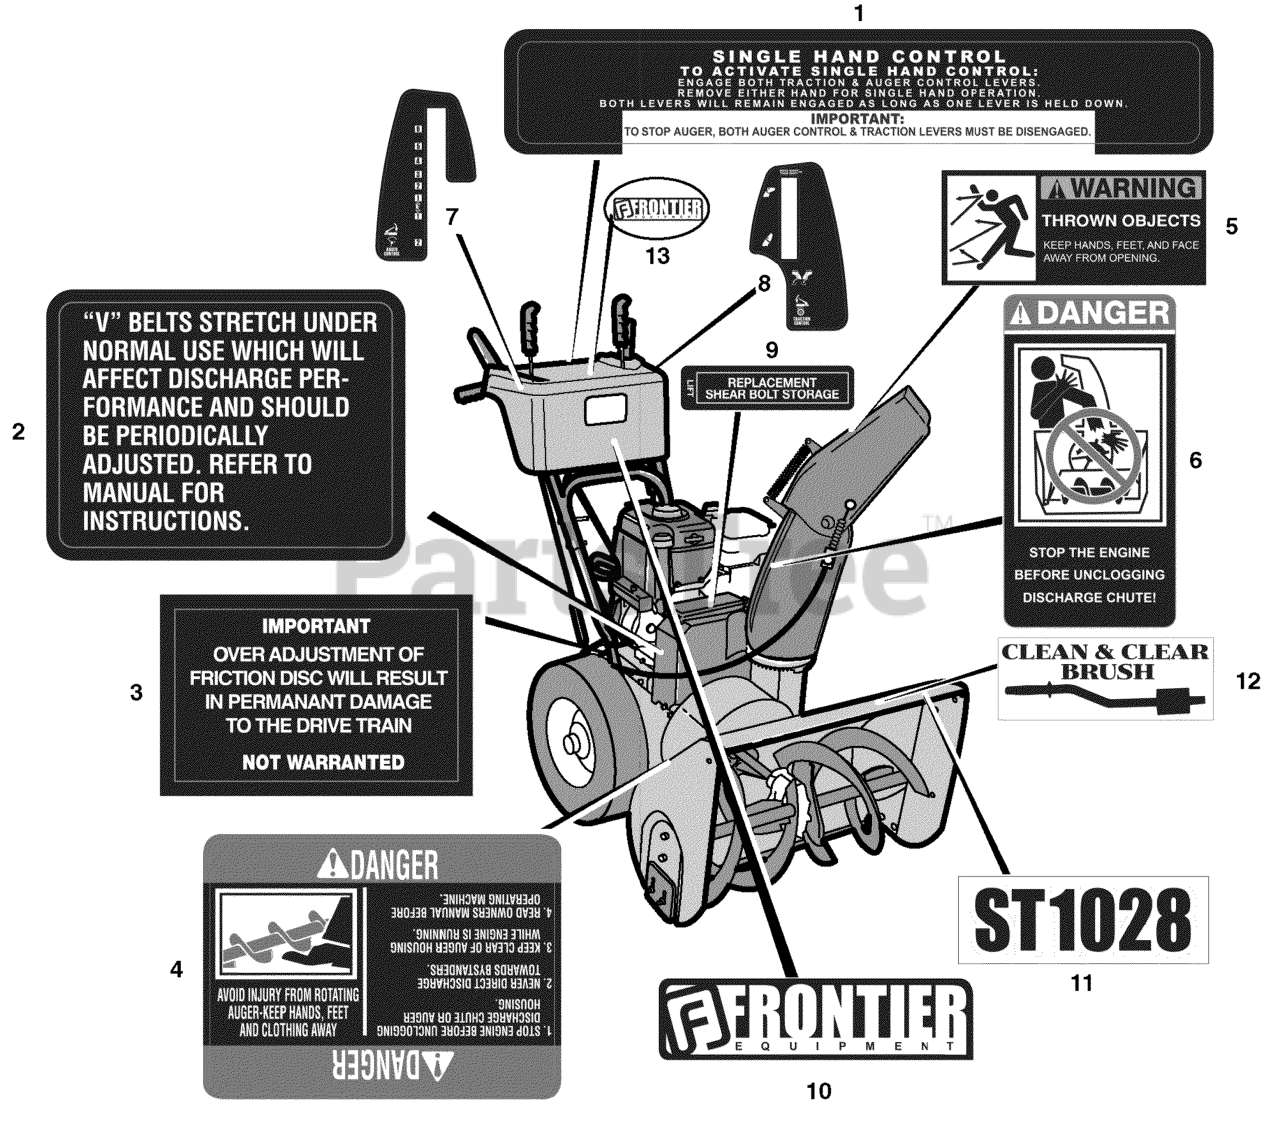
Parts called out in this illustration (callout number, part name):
1	DECAL, SINGLE HAND CONTROL
2	DECAL, V-BELTS
3	DECAL, OVER ADJUSTMENT
4	DECAL, ROTATING AUGER
5	DECAL, DANGER
6	DECAL, UNCLOGGING CHUTE
7	DECAL, SPEED CONTROL
8	DECAL, REMOTE CHUTE CONTROL
9	DECAL, SHEAR BOLTS
10	LOGO NAMEPLATE, FRONTIER
11	DECAL, ST1028
12	DECAL, CLEAN & CLEAR BRUSH
13	DECAL, PANEL
